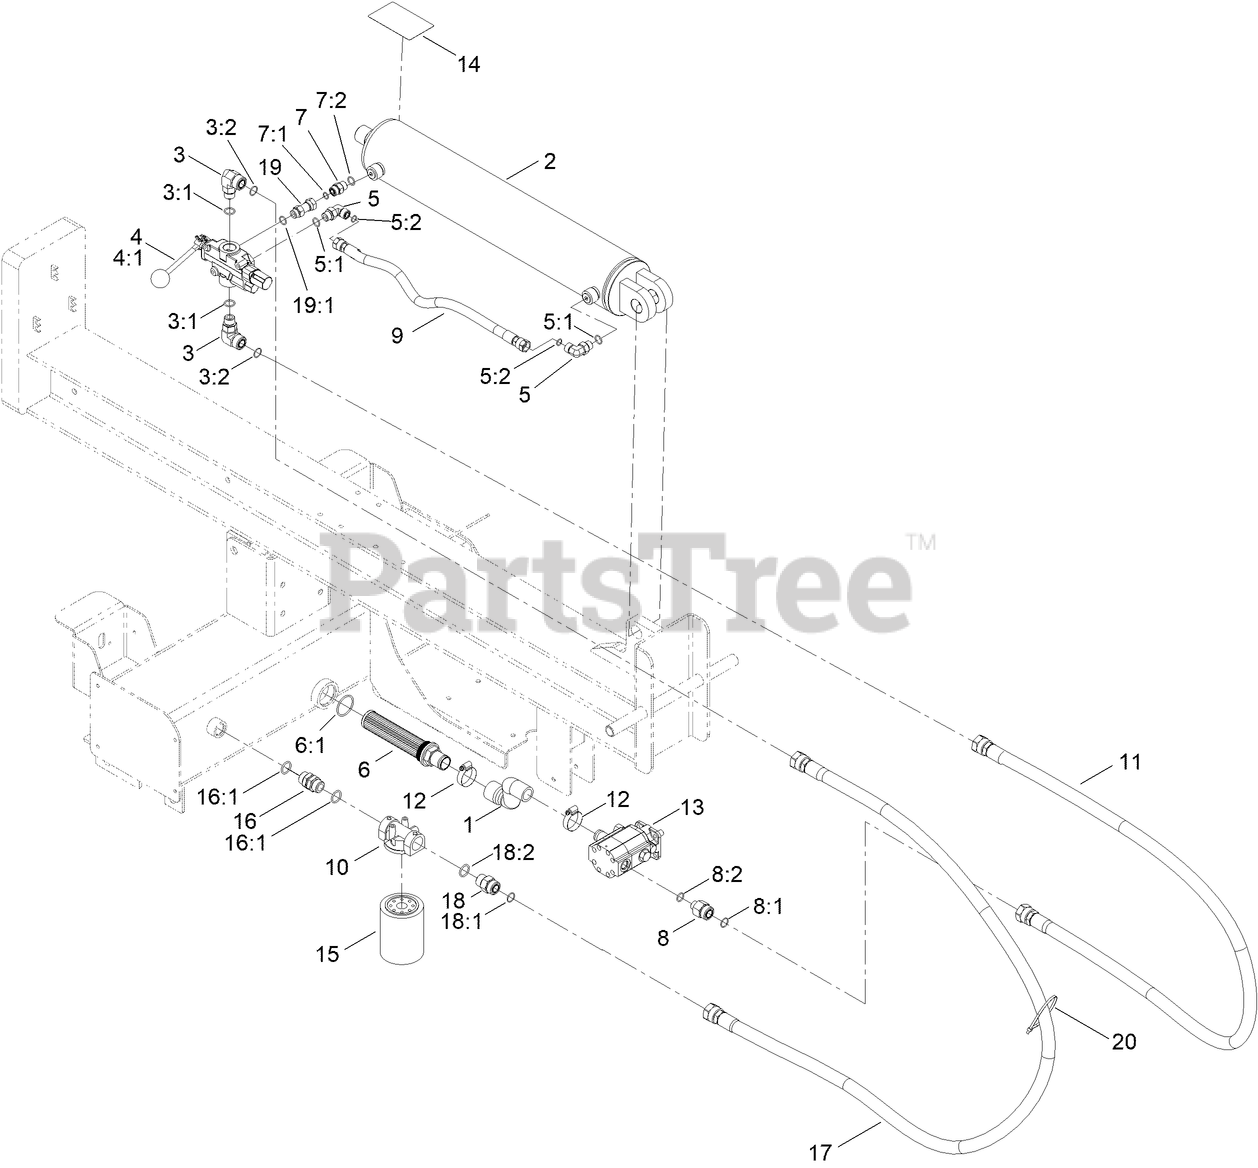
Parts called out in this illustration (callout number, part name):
1	HOSE-MOLDED
2	CYLINDER-HYDRAULIC
3	FITTING-HYD, 90 DEG
3:1	O-RING
3:2	O-RING
4	VALVE-CONTROL
4:1	KIT-HANDLE, VALVE
5	FITTING-ELBOW, 90 DEG
5:1	O-RING
5:2	O-RING
6	STRAINER-TANK, HYDRAULIC
6:1	O-RING
7	FITTING-STRAIGHT
7:1	O-RING
7:2	O-RING
8	FITTING-STRAIGHT
8:2	O-RING
9	HOSE ASM-HYD
10	HEAD-FILTER
11	HOSE ASM-HYD
13	PUMP-HYD
14	DECAL- CAUTION, CONTROL
15	FILTER-OIL, TRANSMISSION
16	FITTING-THREAD, STRAIGHT
16:1	O-RING
17	HOSE ASM-HYD
18	FITTING-HYD, STRAIGHT
18:1	O-RING
18:2	O-RING
19	ADAPTER-HYD
19:1	O-RING
20	TIE-CABLE
